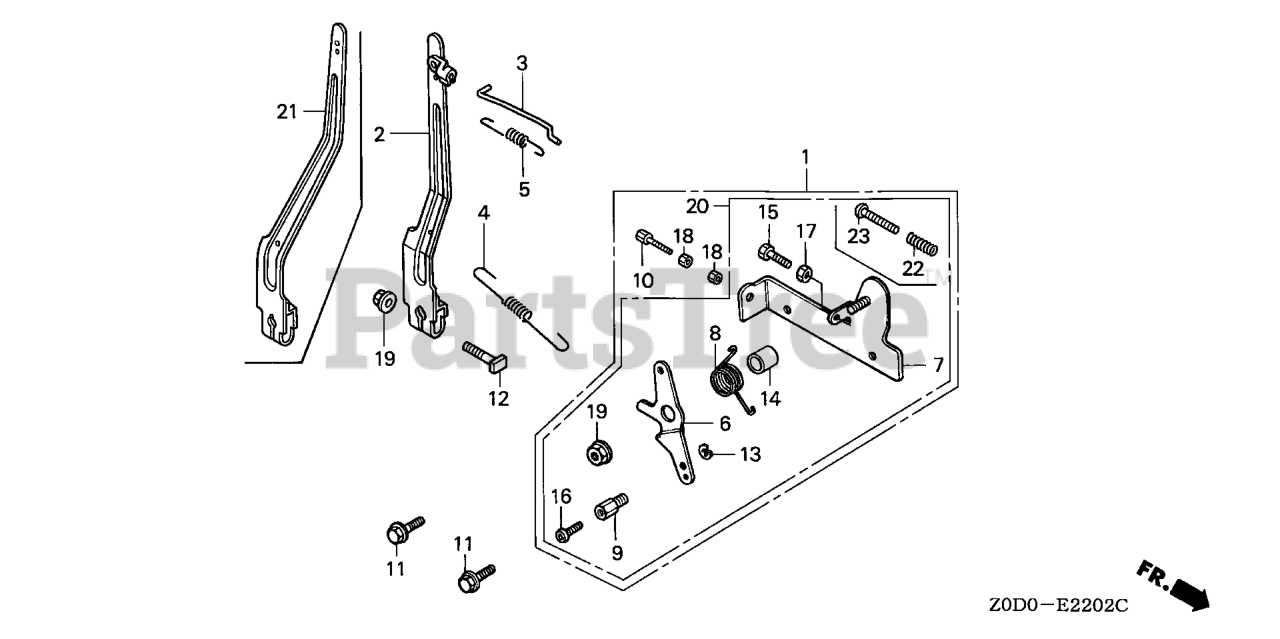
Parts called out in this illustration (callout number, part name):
2	ARM, GOVERNOR
3	ROD, GOVERNOR
4	SPRING, GOVERNOR
5	SPRING, THROTTLE RETURN
6	LEVER, CONTROL (REMOTE)
7	BASE, CONTROL
8	SPRING, RETURN
9	HOLDER, WIRE
11	BOLT, FLANGE (6X14)
12	BOLT, GOVERNOR ARM
13	CIRCLIP (5MM) Use from Engine SN 2327377.
14	COLLAR, CONTROL LEVER
15	BOLT, HEX. (5X20)
16	SCREW, PAN (4X6)
17	NUT, HEX. (5MM)
19	NUT, FLANGE (6MM)
20	CONTROL ASSY.
